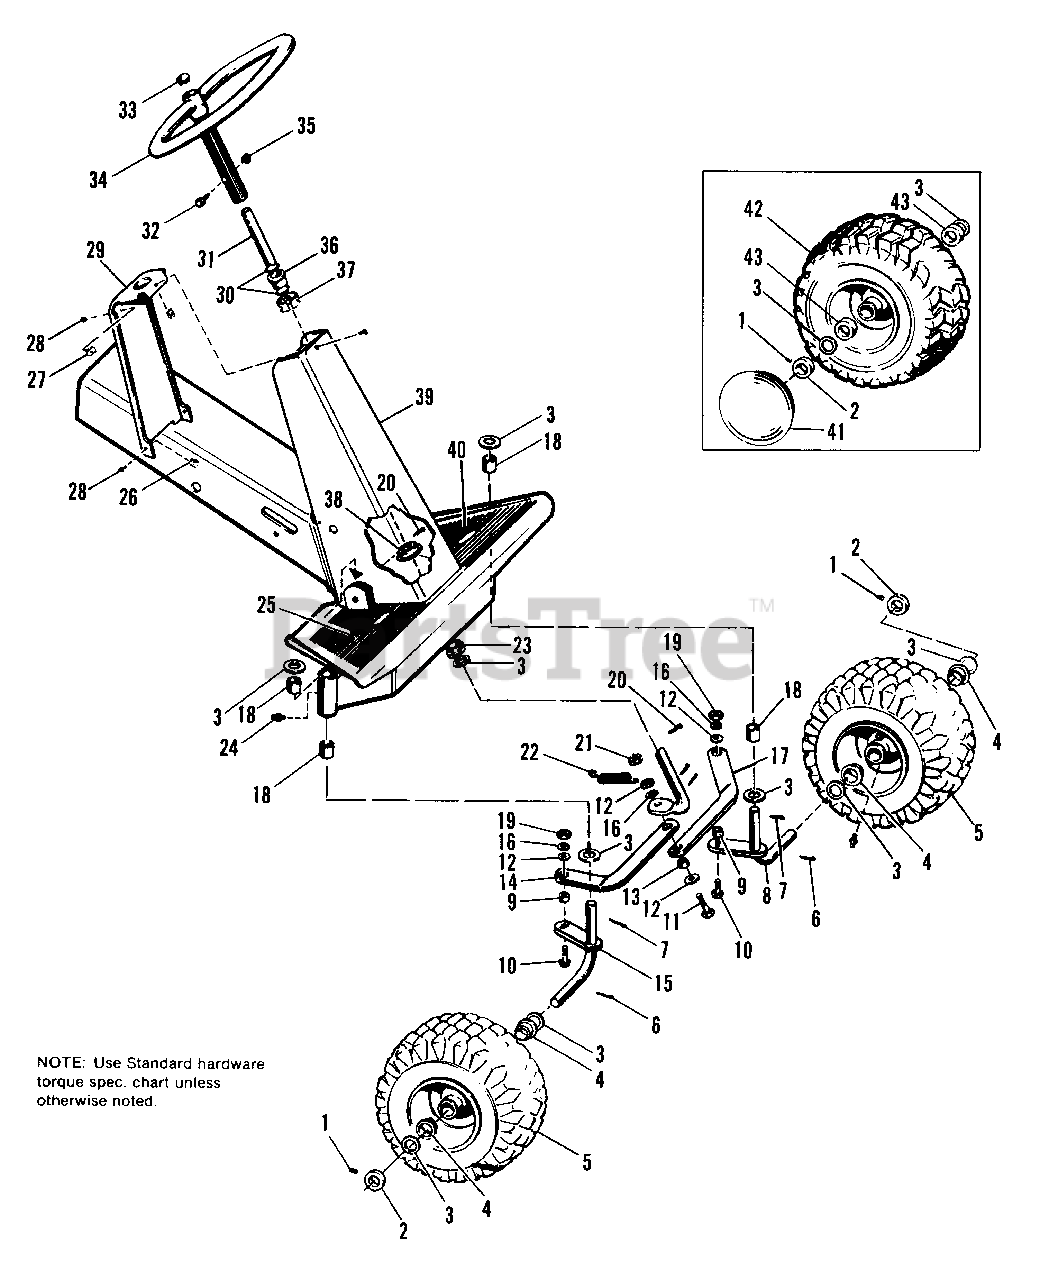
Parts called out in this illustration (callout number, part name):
1	SETSCREW, Cup Pt., 5/16-18 x 5/16
2	COLLAR, Set
5	WHEEL & TIRE ASSY., Front
6	PIN, Cotter, 3/16 x 1-1/4
7	PIN, Cotter, 5/32 x 1
8	SPINDLE ASSY., L.H.
10	SCREW, Hex, Whizlock, Flange, 3/8-16 x 1-1/4
11	CAPSCREW. Hex Hd., 3/8-16 x 2
12	WASHER, Plain, 3/8
14	LINK, Steering, R.H.
15	SPINDLE ASSY., R.H.
16	LOCKWASHER, 3/8
17	LINK, Steering, L.H.
19	NUT, Hex, Full, 3/8-16
20	PIN, Cotter, 5/32 x 1-1/4
21	LOCKNUT, Hex, 3/8-16
24	FITTING, Grease, #1641
25	PAD, Foot Rest, R.H.
26	NUT. Speed
27	NUT, Speed
28	SCREW, Self Tapping, #10 x 1/2
30	RING, Snap
31	SHAFT. Steering
32	CAPSCREW, Hex Hd., 5/16-18 x 1-1/4
33	BUTTON, Plug
34	HANDLE ASSY., Steering
35	LOCKNUT, Hex, 5/16-18
37	RETAINER, Steering Bushing
38	CUP. Steering Shaft
39	FRAME & AXLE ASSY., Front
40	PAD, Foot Rest. L.H.
41	CAP. Hub, Front Wheel
42	WHEEL & TIRE ASSY. Front
